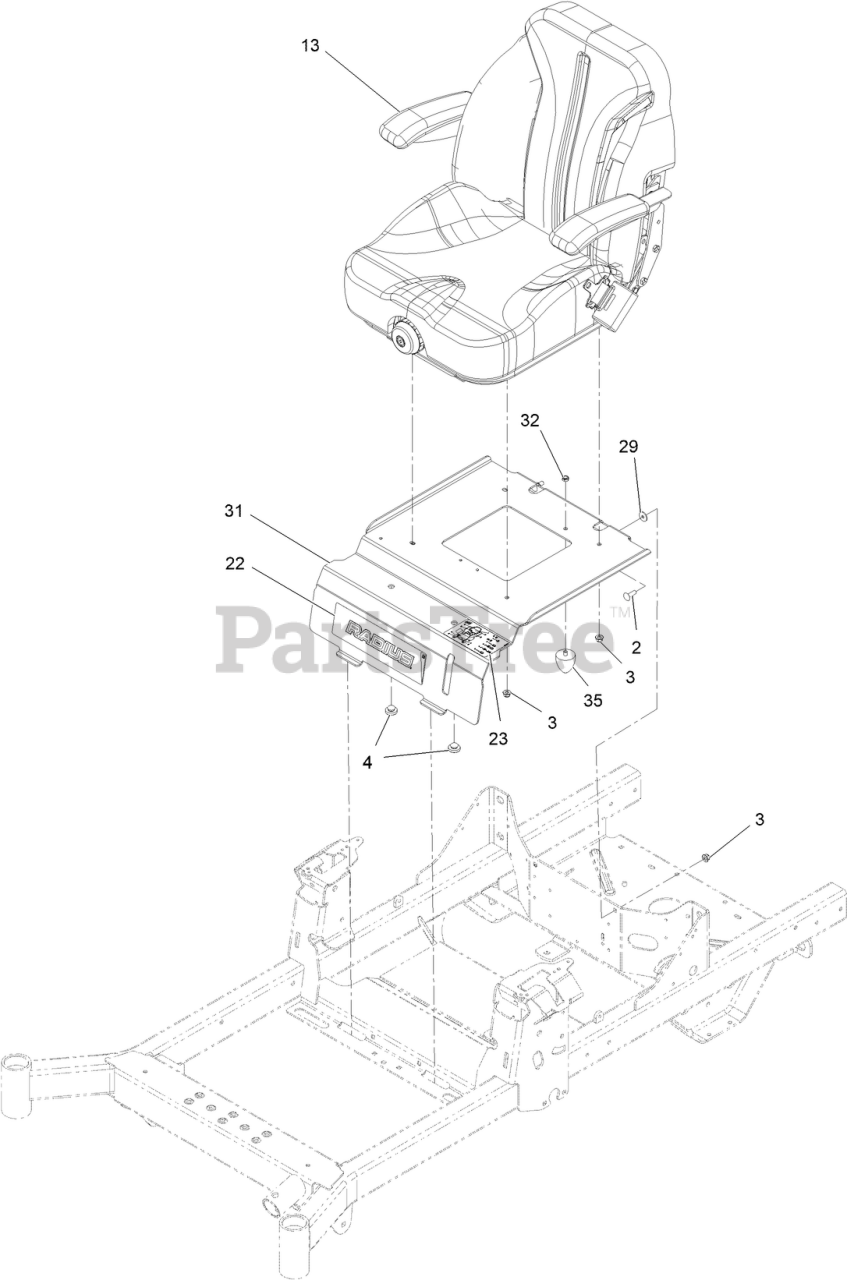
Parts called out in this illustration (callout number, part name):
2	SCREW-CARR
3	NUT-HF, NI
4	BUMPER-SEAT
13	ASM-SUSP SEAT
22	DECAL-RADIUS LOGO
23	DECAL-AID, SERVICE
31	PLATE-FIXED SEAT
32	NUT-LOCK, NI
35	BUMPER-RUBBER
